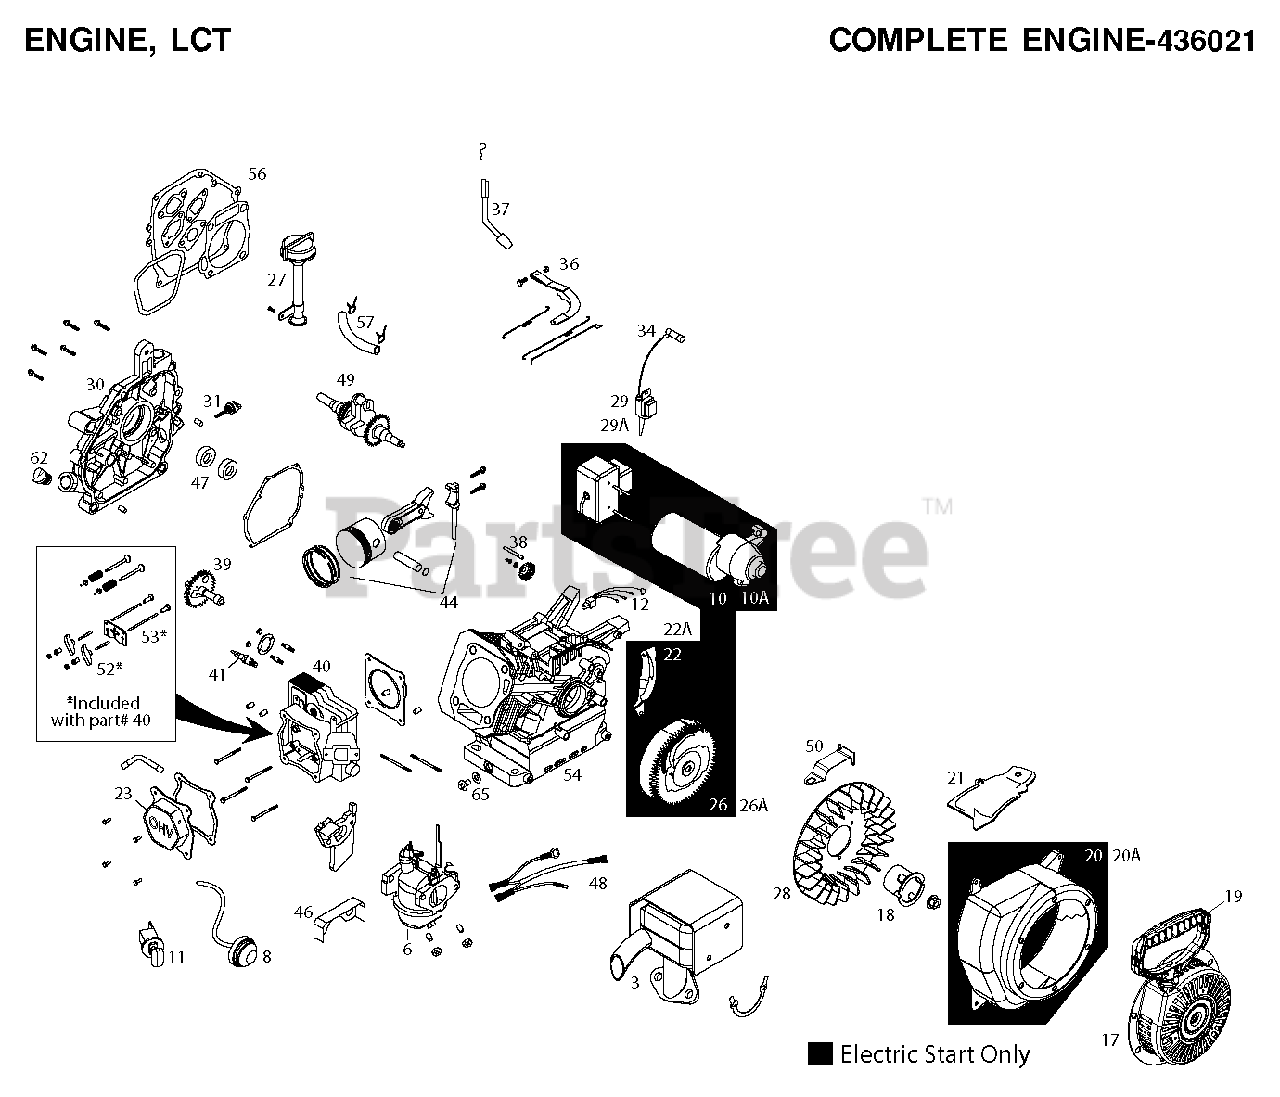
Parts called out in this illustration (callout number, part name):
3	MUFFLER.LCT.SINGLE/STAGE.SNOW.
6	CARBURETOR.SNOW.LCT.136CC
8	BULB.FUEL.PRMR.W/HOSE(SKSNO306
10	STARTER.ASM.ELEC.(SKSNO411)
11	SWITH.KEY.ASSEM.SNOW.SINGLE.ST
12	CDI.BOX SNOW
17	RECOIL.STRT.ROUND(BLK) SNOW
18	CUP.STARTER.LCT.136CC.SNOW
19	STARTER.GRIP.SNOW.LCT.SKSN0603
20	HOUSING.BLWR.ELEC.START.136CC
20A	HOUSING.BLOWER.MANUAL.136CC
21	SHIELD.CYLINDER.LCT.136CC
22	SHIELD.FLYWHEEL.ELEC.START.136
23	COVER.VALVE.ASSEM.LCT.136CC
26	FLYWHEEL.ELEC.START.LCT.136CC
26A	FLYWHEEL.MAN.START.136CC.LCT
27	TUBE.OIL.HIGH.FILL.LCT.136CC
28	FAN.FLYWHEEL.LCT.SING/STAGE.SN
29	KIT.IGNITION.COIL(SK208-2500)
29A	208CC IGN COIL (STD)
30	COVER.CRANKCASE,LCT,136CC
31	DIPSTICK SMALL
34	SPARK.PLUG.BOOT.SNW,SKSN4691.1
36	ARM.ASM.GOVNR.LCT.136CC
37	SHAFT.GOVERNOR.LCT.136CC
38	GOVENOR.GEARS ASM(SK2082900)
39	CAMSHAFT.LCT.136CC.
40	HEAD.CYLINDER.ASSEM.LCT.136CC
41	SPARK.PLUG(2083810)
44	PISTON.&.ROD.ASSEM.LCT.136CC
46	SHIELD.VAPOR.SNOW
47	KIT.ENGINE.SEAL.LCT.136CC
48	HARNESS.WIRE.SINGLE.STAGE.LCT
49	CRANKSHAFT.LCT.136CC
50	SPEED.CTRL.BRKT.(SKSN0150)
52	KIT ROCKER.ARM.LCT
53	KIT.PUSH.ROD.LCT.136CC
54	CYLINDER.ASSEM.LCT.136CC
56	KIT.GASKET.LCT.136CC
57	KIT.FUEL.HOSE.208CC.SING/STAGE
62	NON REMOVABLE PLUG
65	KIT.OIL.DRAIN.PLUG(SK2089911
